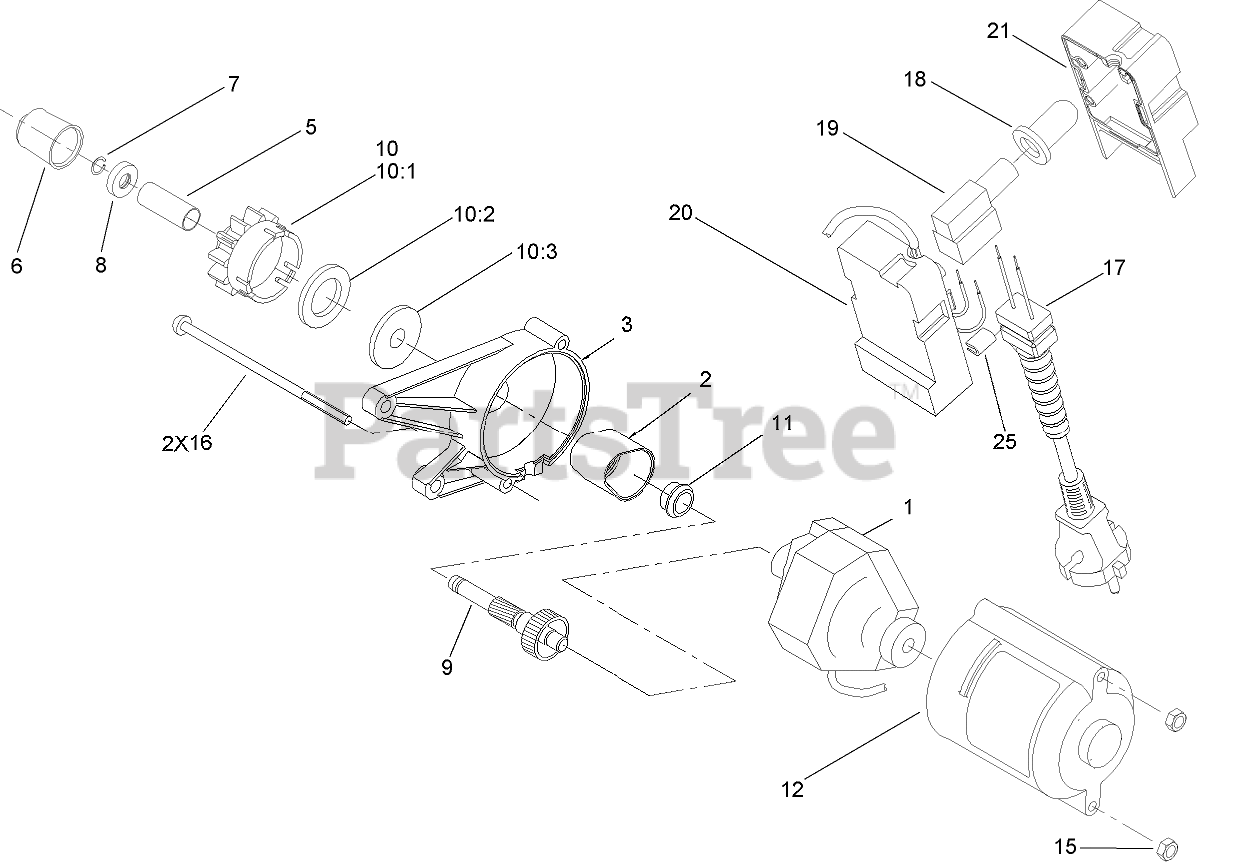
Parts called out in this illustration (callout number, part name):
1	MOTOR-STARTER
2	COVER-GEAR
3	HOUSING-UPPER, STARTER
5	SPRING
6	CAP-PINION
7	RING-LOCK
8	STOP-PINION
9	SHAFT AND GEAR ASM
10	PINION ASM
10:2	PINION
10:3	RING-RUBBER
11	BUSHING
12	HOUSING-LOWER, STARTER
15	NUT-LOCK, NI
17	PLUG-POWER 230 VOLT
18	BOOT-SWITCH
19	SWITCH-STARTER
20	SWITCH-BASE, HOUSING
21	HOUSING-CAP, SWITCH
25	SPACER-PLUG
